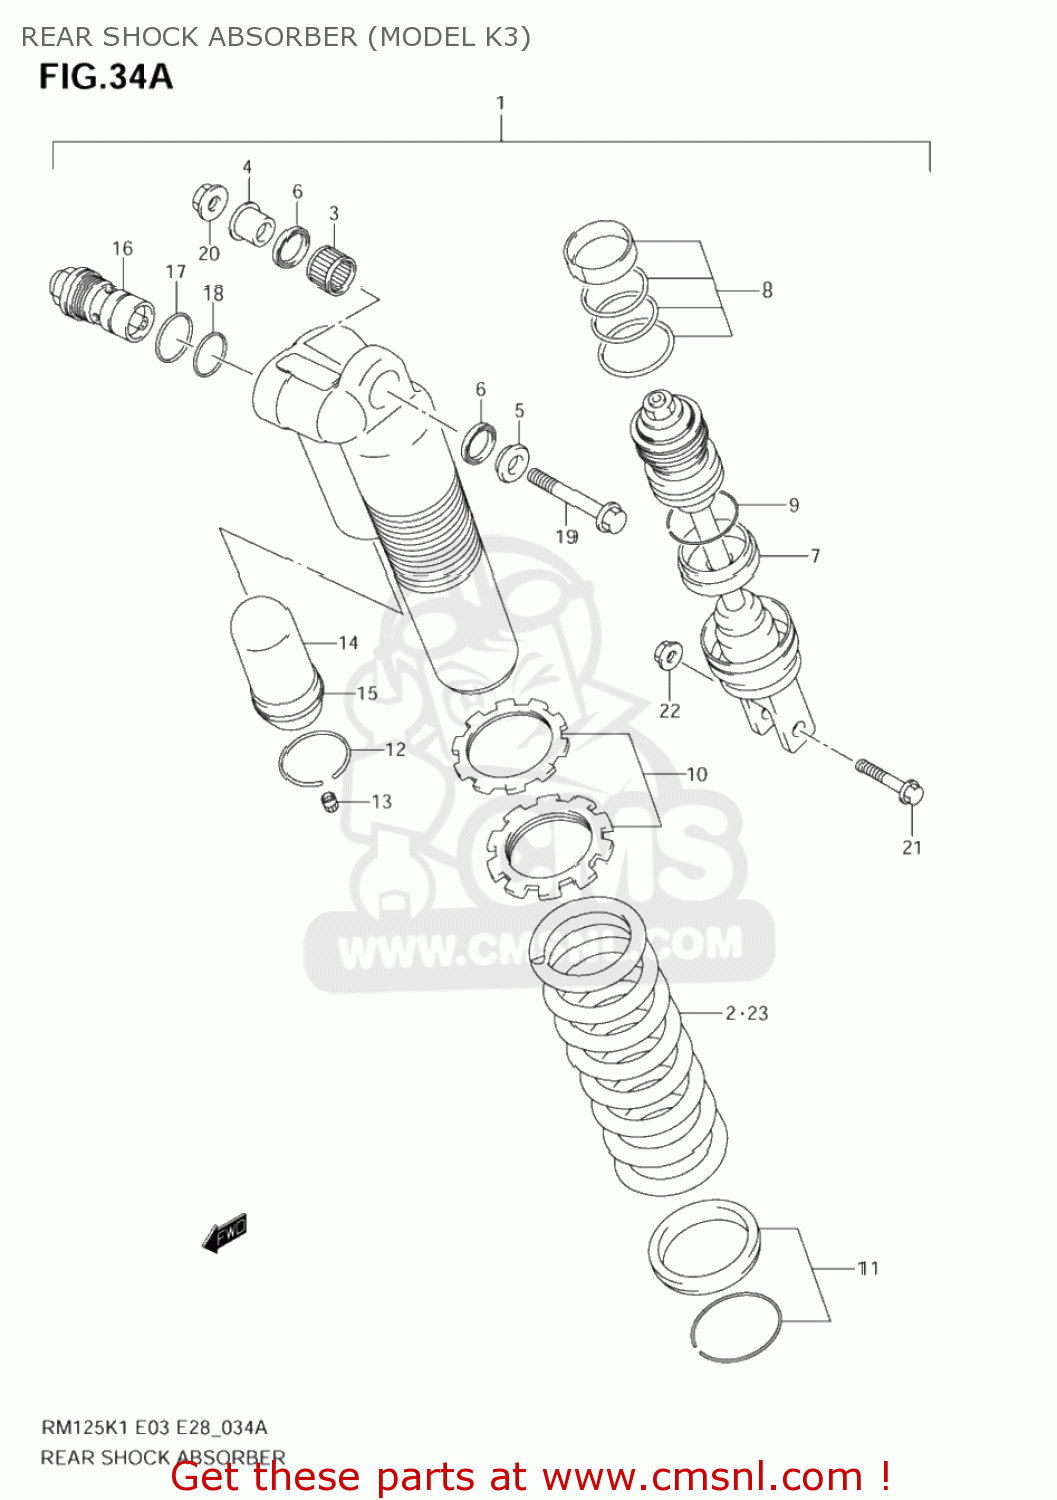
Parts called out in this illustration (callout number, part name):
1	ABSORBER ASSY,RR SHOCK
2	SPRING,RR(K=4.9)
3	BEARING(16X22X12)
4	SPACER,UPPER BRG,R
5	SPACER,UPPER BRG,L
6	SEAL,OIL(16X22X2.5)
7	ROD,PISTON
8	O RING SET
9	RING,STOPPER
10	ADJUSTER SET
11	SPRING SEAT SET
12	RING,STOPPER
13	CAP
14	BLADDER
15	CAP, CHAMBER
16	BOLT,PLUG
17	O RING
18	O RING,CTR BOLT UPR
19	BOLT(10X60)
20	NUT
21	BOLT(10X44.5)
22	NUT
23	SPRING,RR(K=4.6)
